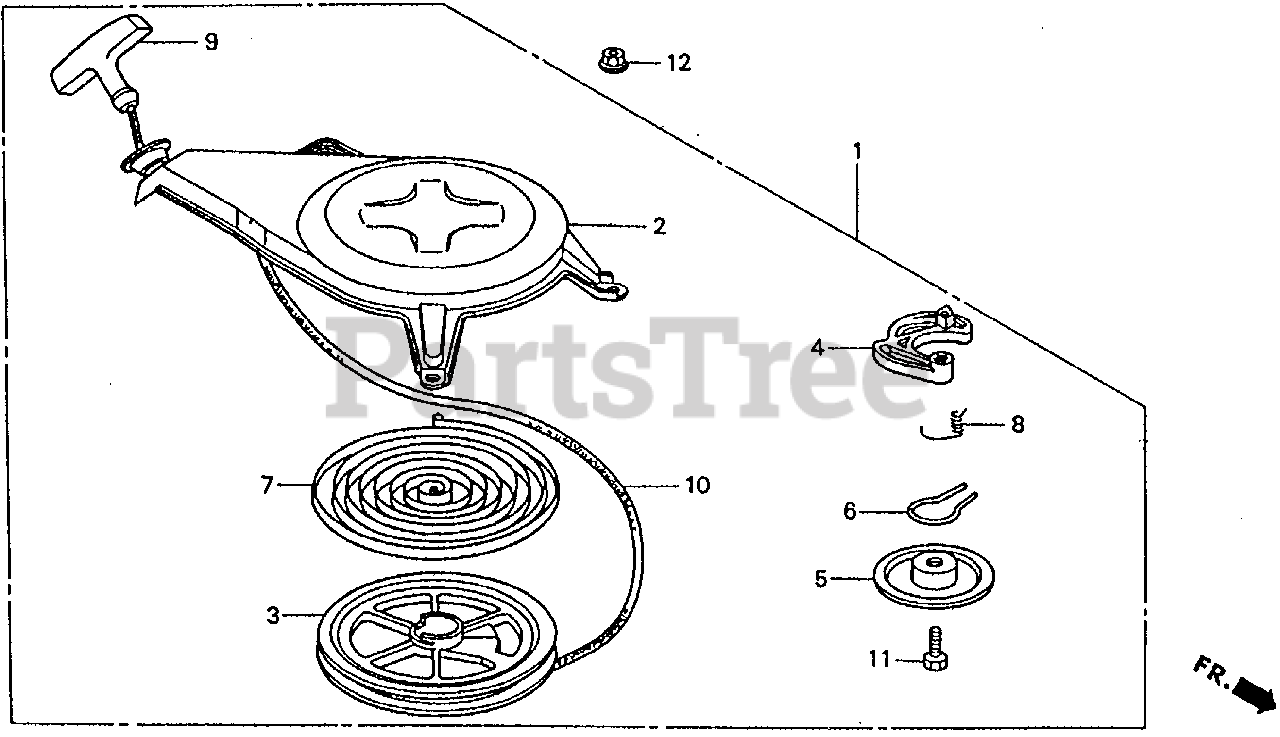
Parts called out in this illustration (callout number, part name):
1	STARTER ASSY., RECOIL
2	CASE, RECOIL STARTER
3	REEL, RECOIL STARTER
4	RATCHET, STARTER
5	PLATE, FRICTION
6	SPRING, FRICTION
7	SPRING, RECOIL STARTER
8	SPRING, RETURN
9	KNOB, STARTER
10	ROPE, RECOIL STARTER (#4X65") (N/A: USE ALTERNATE P/N 08540-ZG921-11)
11	BOLT, HEX. (6X20)
12	NUT, FLANGE (5MM)
